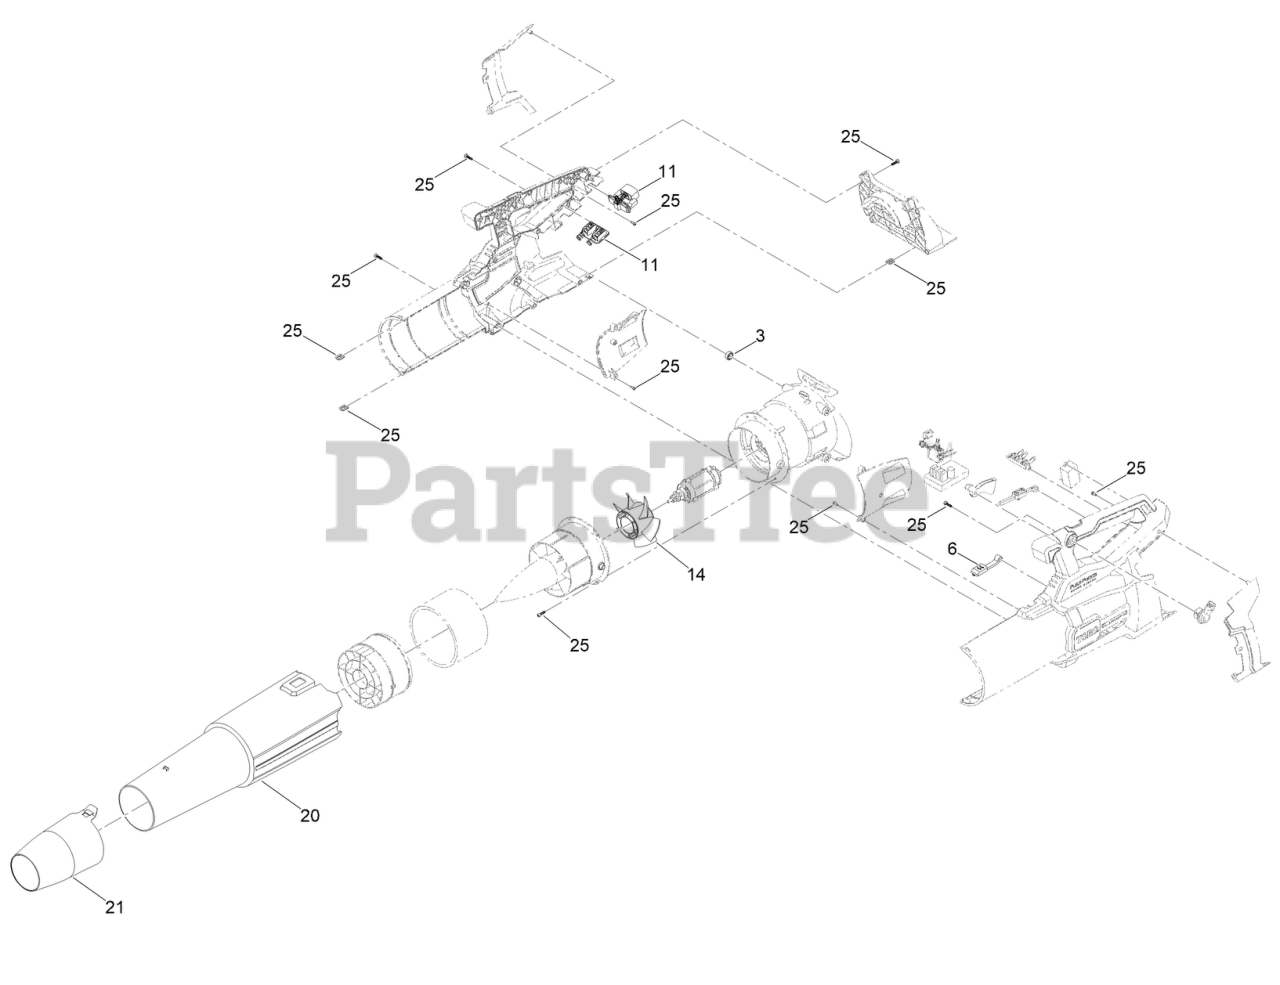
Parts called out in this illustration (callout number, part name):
3	60V AXIAL BLOWER ISOLATOR KIT
6	BLOWTUBE RELEASE SERVICE KIT
11	60V AXIAL BLOWER BATTERY LATCH
14	60V BLOWER FAN SERVICE ASM
20	60V AXIAL BLOWER BLOW TUBE
21	60V AXIAL BLOWER REDUCER NOZZLE
25	60V AXIAL BLOWER HARDWARE KIT
